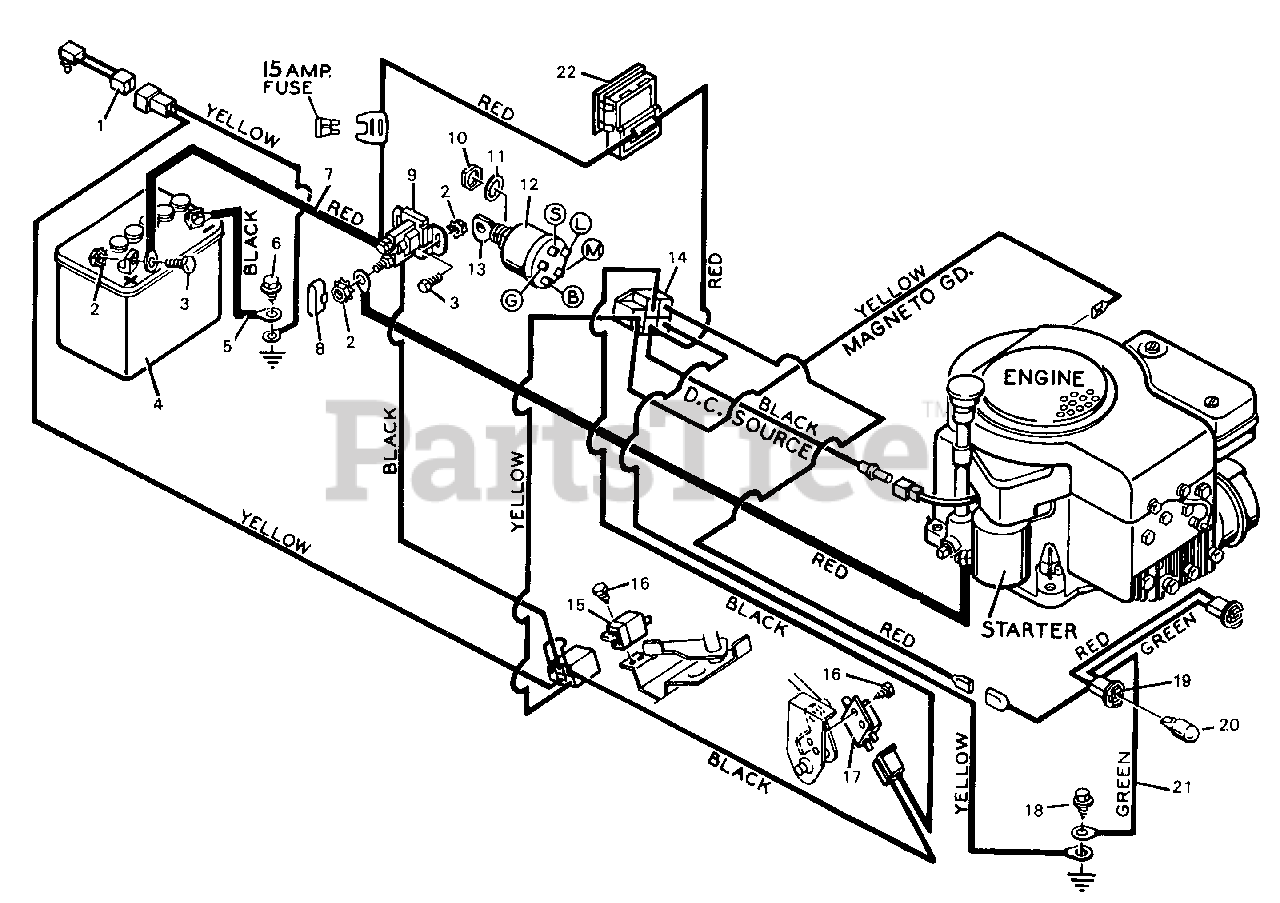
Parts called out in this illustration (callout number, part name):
1	SWITCH- Seat sensor
2	NUT- Lock
3	BOLT- Hex
4	BATTERY- 30 amp.
5	CABLE- Battery (ground)
7	CABLE- Battery (positive)
8	COVER- Solenoid
9	SOLENOID
10	NUT- Hex
11	WASHER- Shakeproof
12	SWITCH- Ignition
13	IGNITION KEY & RING
14	HARNESS- Chassis wire
15	SWITCH- P.T.O.
17	SWITCH- Clutch
19	SOCKET- Light
20	BULB- Light
21	HARNESS- Light wire
